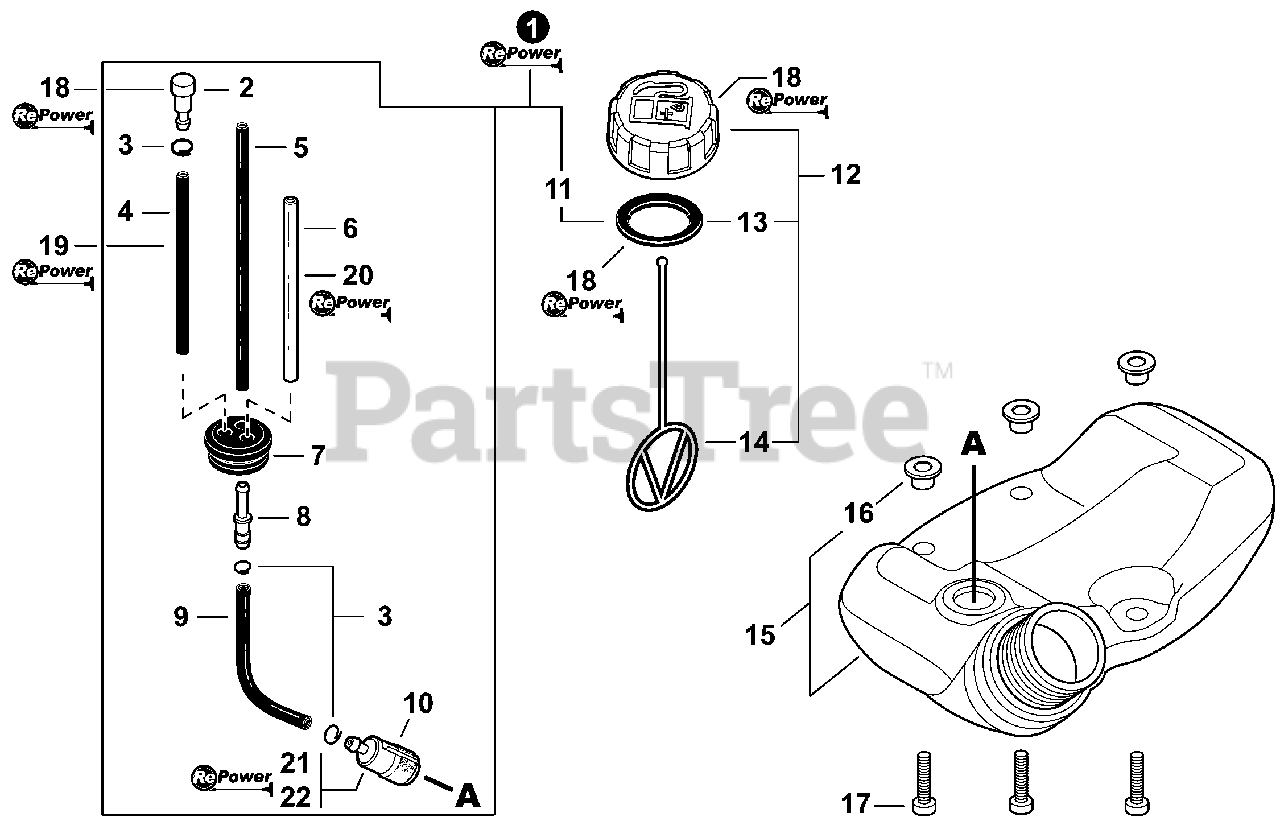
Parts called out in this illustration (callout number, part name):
1	FUEL SYSTEM KIT
2	VENT ASSY
3	CLIP Ø6
4	PIPE, FUEL 3×5×90 BLACK
5	PIPE, FUEL 3×5×74 BLACK
6	PIPE, FUEL 3×6×80 CLEAR
7	GROMMET, FUEL Ø5
8	CONNECTOR, PIPE Ø5ר3.5
9	PIPE, FUEL 3×5×130 BLACK
10	FILTER, FUEL
11	GASKET, FUEL CAP
12	CAP ASSY, FUEL
13	GASKET, FUEL CAP
14	CONNECTOR, CAP L= 123
15	TANK ASSY, FUEL
16	COLLAR 5
17	BOLT, TORX 5×20
18	CAP/VENT KIT - REPOWER
19	BULK PIPE - 3×5 MM BLACK (4 PIECES×2 M)
20	BULK PIPE - 3×6 MM CLEAR (4 PIECES×2 M)
21	TUNE-UP KIT - REPOWER
22	FILTER KIT - REPOWER
